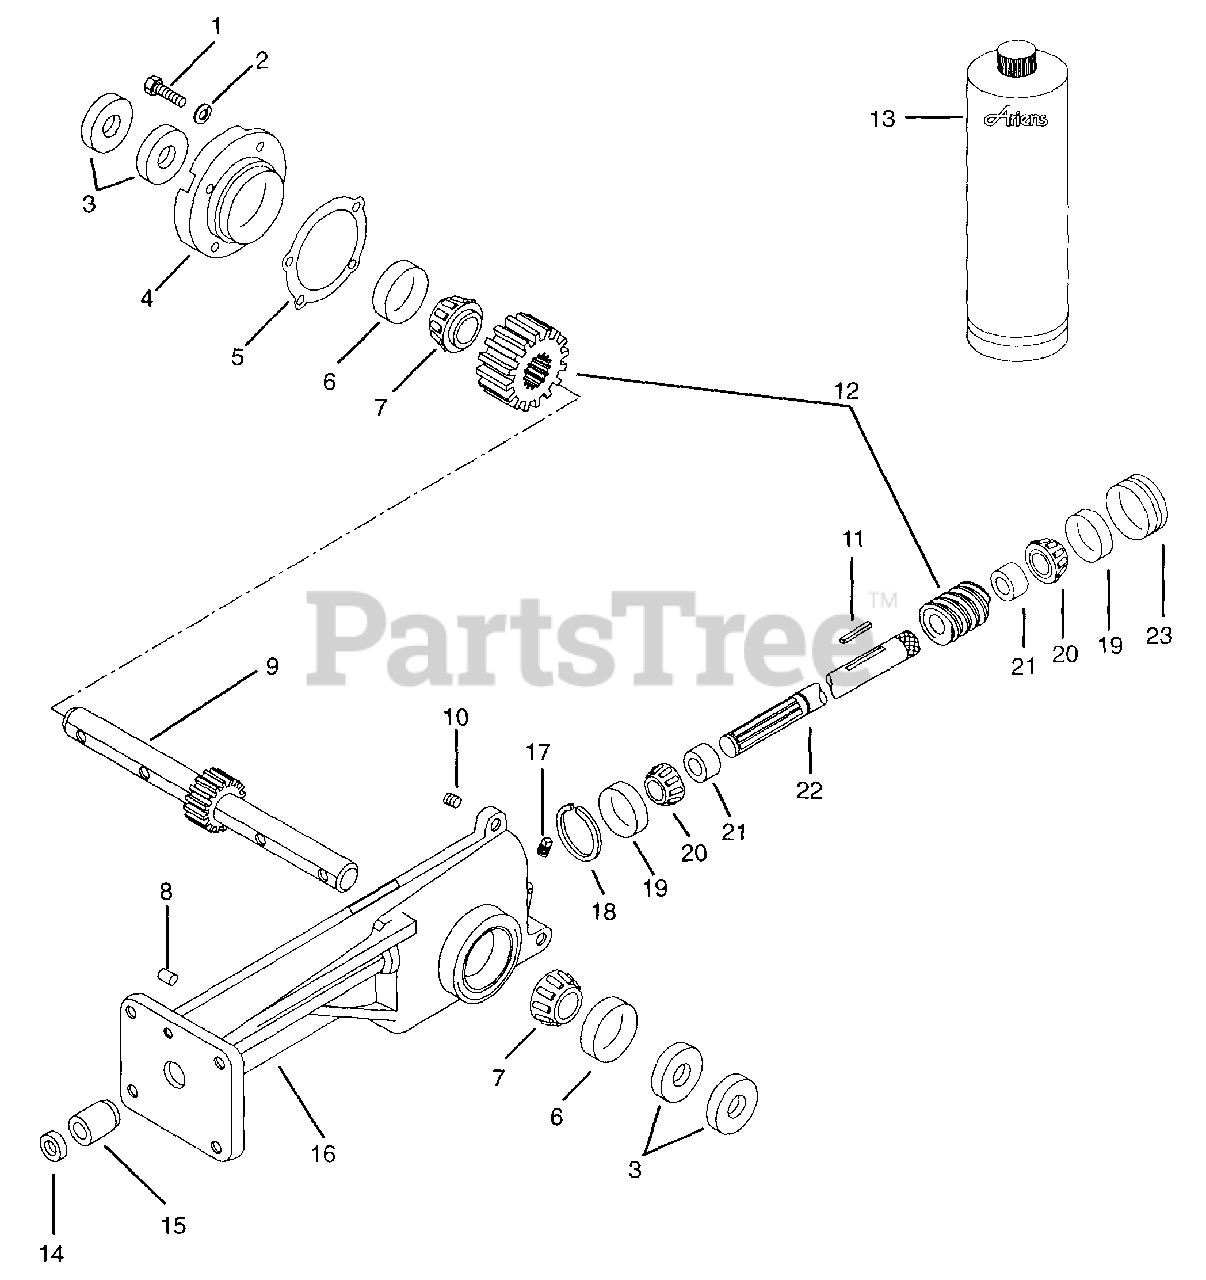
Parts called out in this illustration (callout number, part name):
1	@BLT-HEX .38-16X1.00 GR5 YWZC
2	@WSHR-LK .38X.094 REG YWZC
3	SEAL 1.250X2.00X.250
4	BEARING FLANGE
5	SERVICE KIT
6	BRG-CUP 2.328X.465
7	BRG-CONE 1.25X.66
8	BREATHER
9	TINE SHAFT
10	SCR-SET .25-20X.25 SKHCUPDL
11	KEY-WDRF .188X1.00X.438 SAE13
12	WORM AND WORM GEAR ASSEMBLY
13	ARIENS 16 OZ.BOTTLE OF L2 LUBE
14	SEAL .750X1.000X.125
15	BRG-NEEDLE .750X1.0X.62
16	TILLER GEARCASE - C.I.
17	PIPE PLUG
18	RG-RTNG-INT 1.781X.062
19	BRG-CUP 1.781X.475
20	BRG-CONE .750X.61
21	BSHG, SPCR .755X1.12X.50 PM
22	WORM SHAFT
23	ADJUSTMENT PLUG
